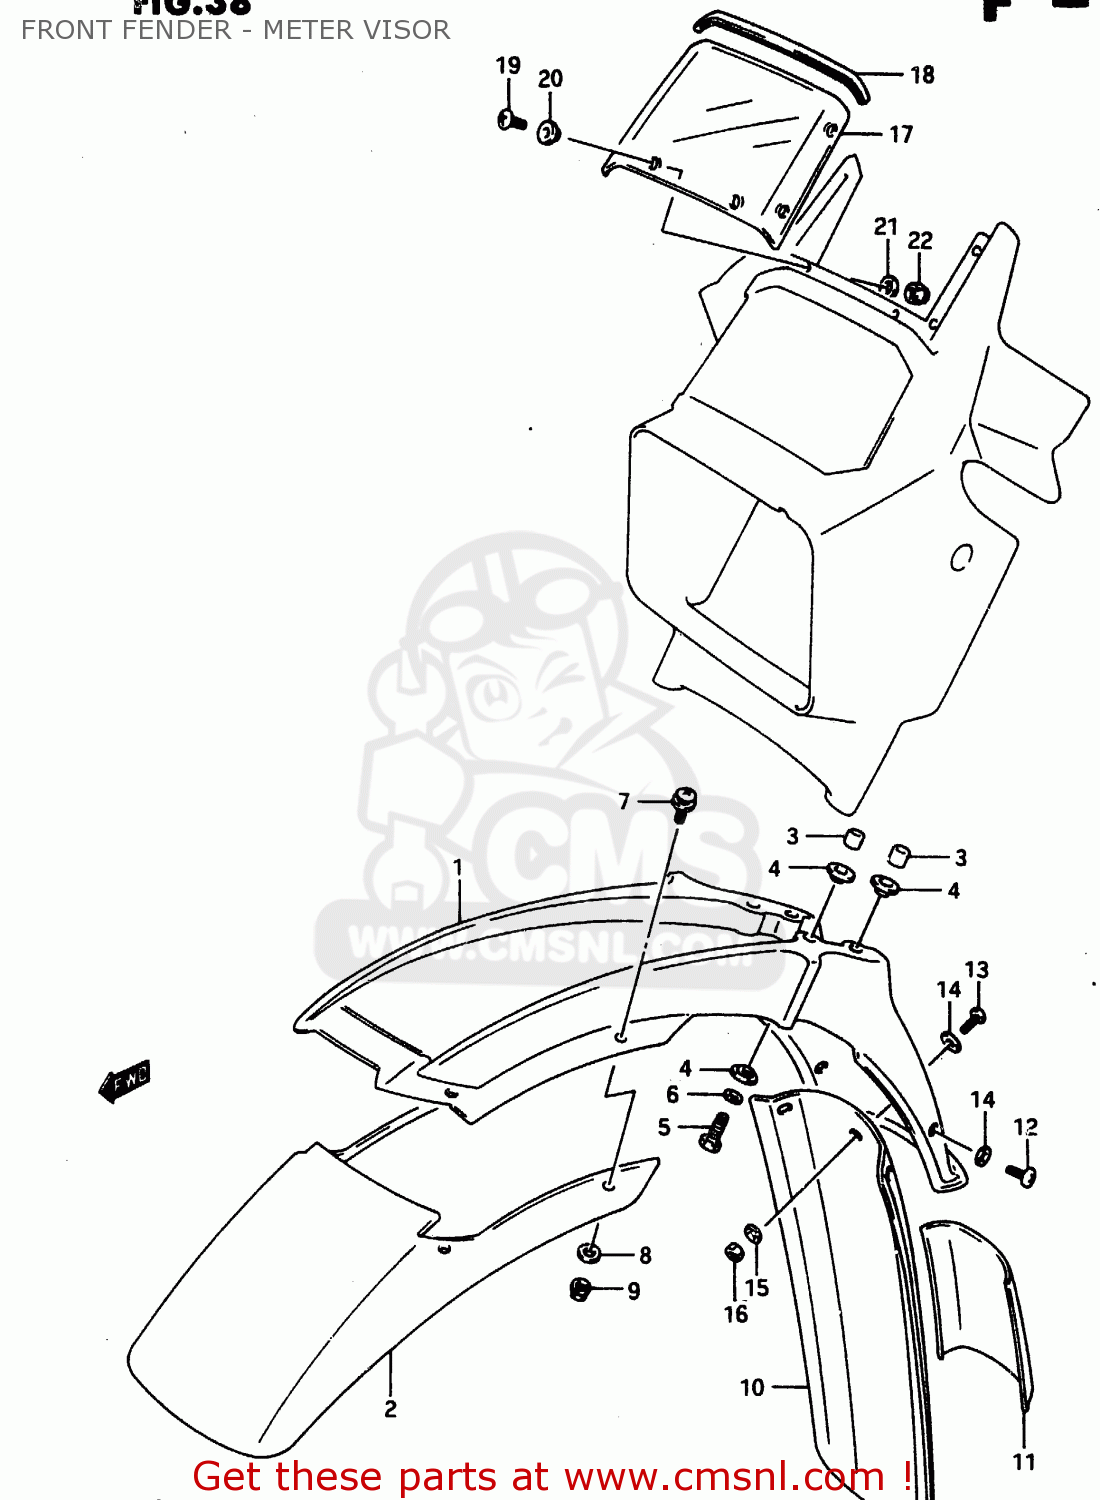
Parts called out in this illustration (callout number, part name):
1	FENDER,FR,R
2	FENDER, FRONT (RED)
3	SPACER(6.1X9X7.5)
4	WASHER
5	BOLT
6	WASHER,LOCK
7	SCREW (6X16)
8	WASHER (6.7X16X1.8)
9	NUT
10	MUD FLAP, FRONT FENDER
11	PROTECTOR SEAT
12	SCREW
13	SCREW, CENTER
14	WASHER (6.7X16X1.8)
15	WASHER,LOCK
16	NUT 6MM
17	VISOR, METER
18	MOLDING
19	SCREW 5X10
20	CUSHION
21	WASHER,5MM
22	NUT
